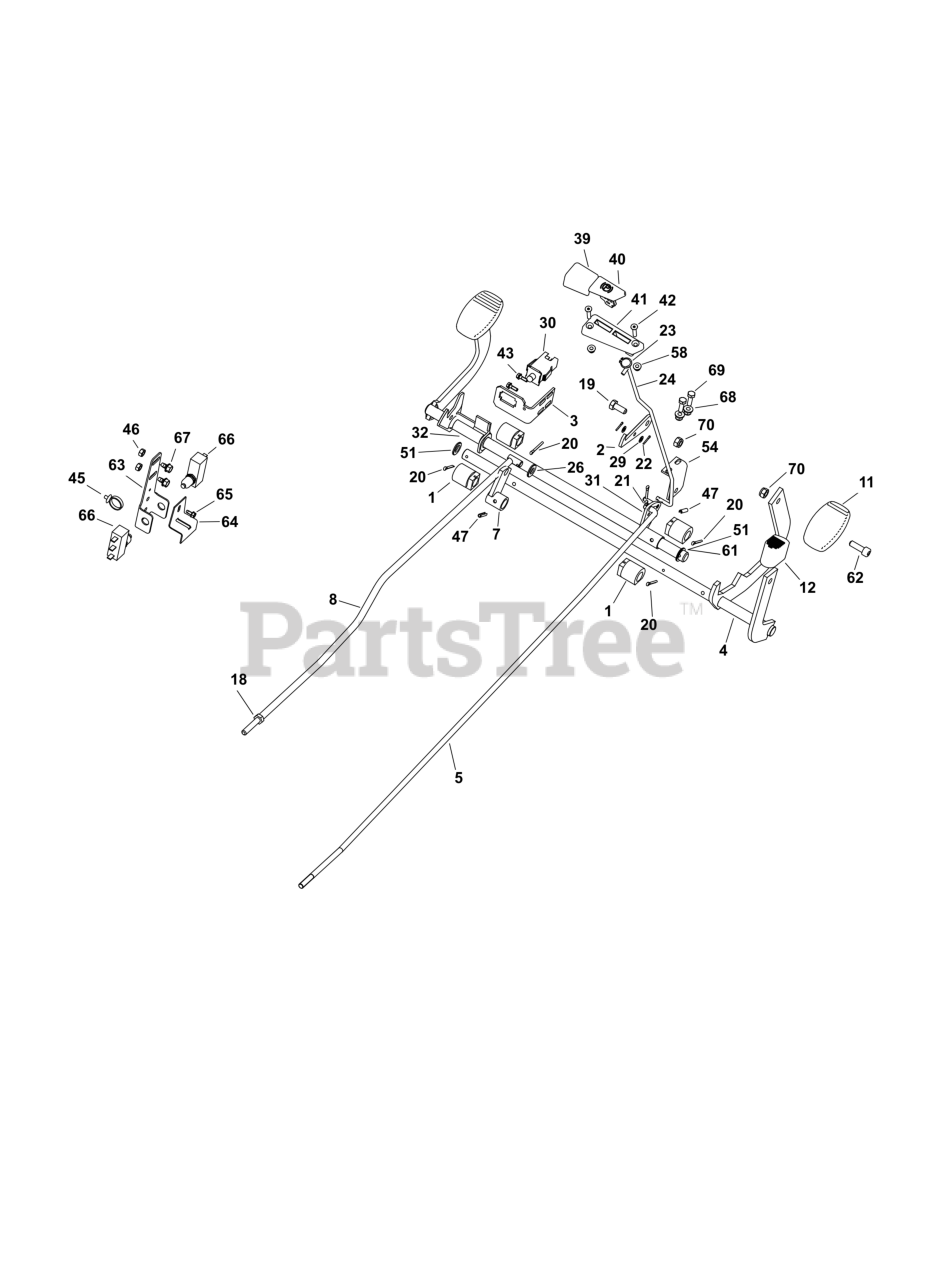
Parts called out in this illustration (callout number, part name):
5	ROD, Brake
11	PAD, Rubber
12	PAD, Foot
24	ROD, Brake
32	BRAKE, Pedal
66	MICROSWITCH
